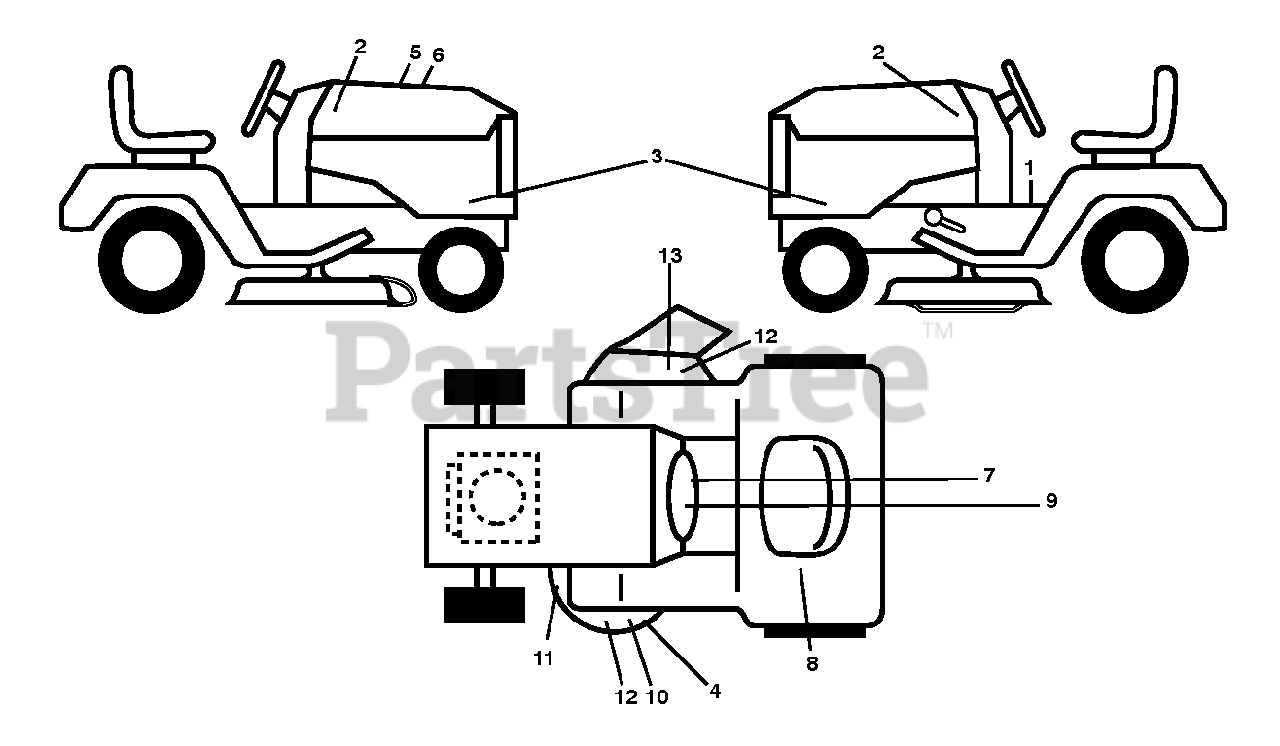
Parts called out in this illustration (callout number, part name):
1	DECAL.FENDER.WARNING.ENGLISH
2	DECAL.BADGE.170MM.TEXTLOGO.
3	Decal, Side Panel HUSQGT YT4
4	Deck Decal, WA
5	DECAL.WARNING.CUST.RESP.E85.
6	Decal, Replacement Kohler KT7 TGB 54F
7	Warning Decal, Spark Arrest
8	DECAL.RESERVEFUELSELCTR.ENG
9	DECAL CARB EMISS.CA.HUSQ
10	Deck Decal, 48"
11	DECAL.MOWER.SCH.48/54.PREM
12	DECAL.DECK.CLEARCUT.NOSTEP
13	DECAL.TRACT/ZTR.DECKWARN.HUSQ
